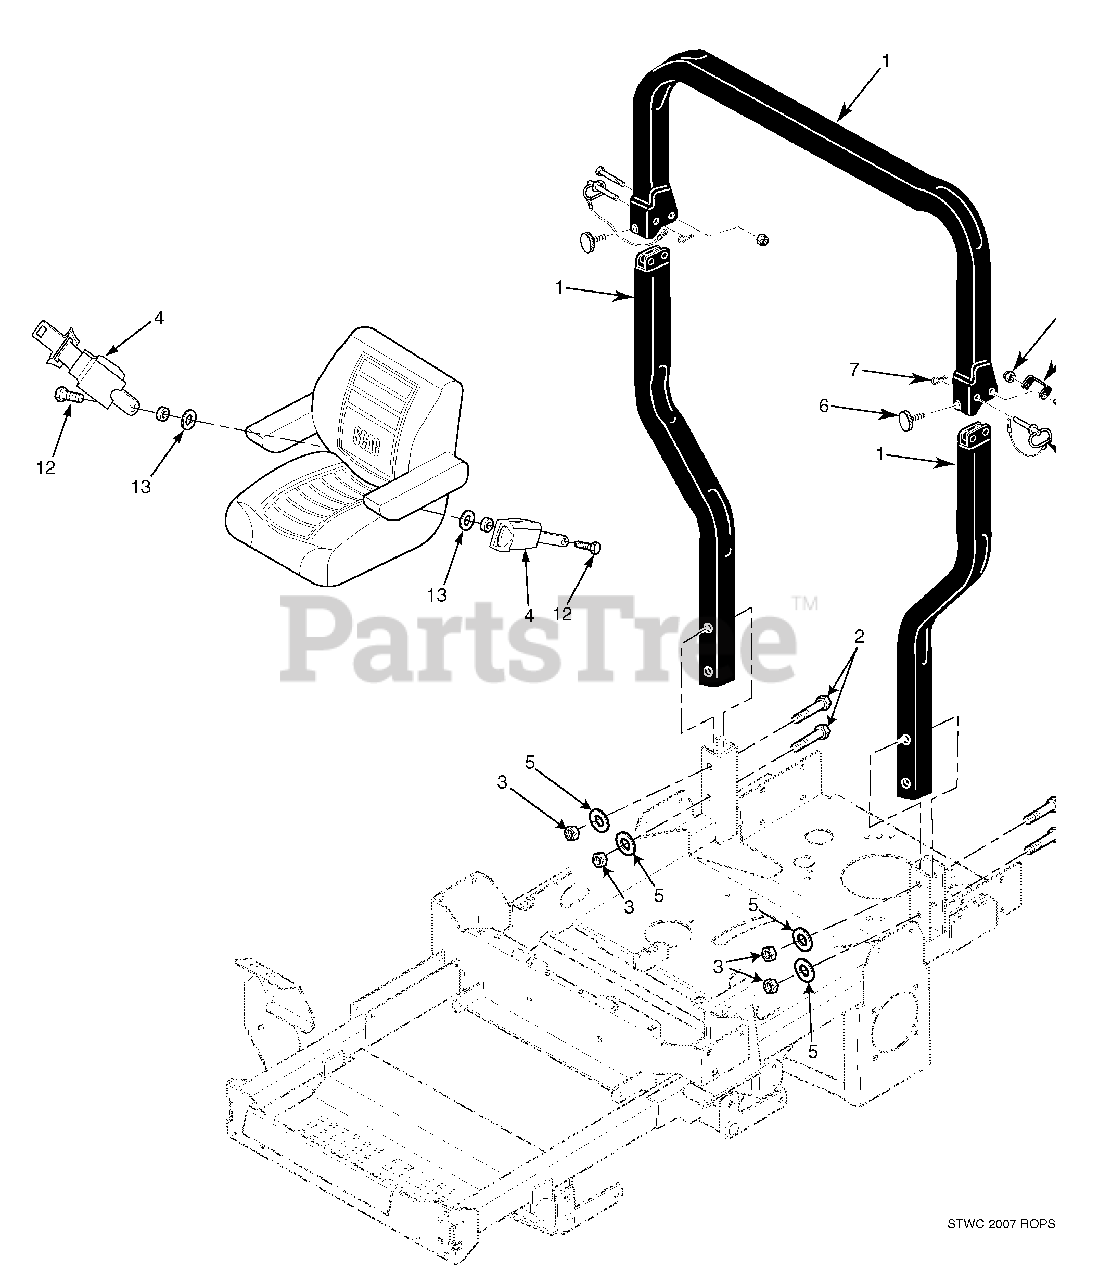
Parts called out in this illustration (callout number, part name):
1	STWC Foldable ROPS
2	Bolt, Hex Hd. 1/2-13 x 3-1/2"
3	Nut, Center Lock 1/2-13
4	Retractable Seat Belt
5	Flatwasher, 1/2 (.562 x 1.375 x .109")
6	Thumb Screw, 5/16-18 NC x 3/4"
7	Hair Pin, Cotter
8	Pin
9	Nut, Center Lock 1/2-13
10	Bracket, Stop
11	Bolt, Hex Hd. 1/2-13 x 3-1/2"
12	Bolt, Hex Hd. 7/16-20 x 1"
13	Flatwasher, 7/16 (.500 x 1.25 x .083")
